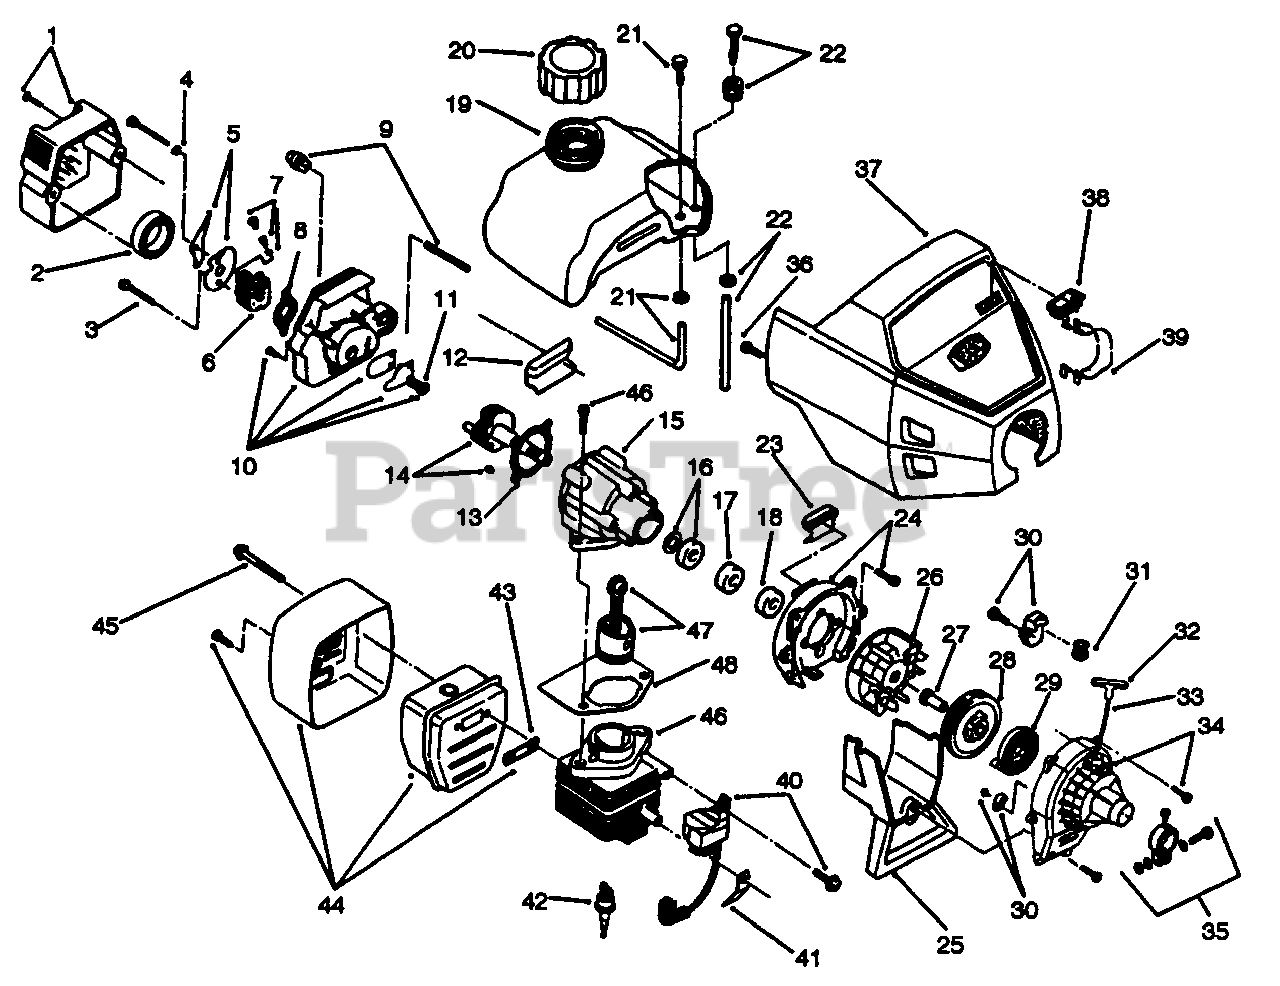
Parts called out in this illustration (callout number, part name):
1	Assy.-Carburetor/Air Clean (Inc. Ref. No.2)
2	Filter-Air Cleaner
3	Screw-Carburetor
4	Washer-Wave
5	Choke-Lever and Plate
6	Assembly-Carburetor
7	Throttle Adj.-Walbro
8	Gasket-Carb. (10 Pack)
9	Assy.-Primer and Hose
10	Assembly-Carb. Mount (Incl. Ref. No. 11 & 13)
11	Assembly-Reed
12	Pad-Mounting, Rear
13	Gasket (10 Pack)
14	Assembly-Power Shaft
15	Assy.-Crankcase (Incl. Ref. No.14-18)
16	Assembly-Inner Bearing
18	Assembly-Outer Bearing
19	Assemby-Fuel Tank (Incl. Ref. No.20-22)
20	Assembly-Fuel Cap
21	Assembly-Return Line
22	Assembly-Fuel Line
23	Pad-Mounting, Front
24	Assembly-Shroud
25	Shroud Extension & Stand
26	Assembly-Flywheel
27	Square Nut Drive
28	Assembly-Recoil Pulley
29	Spring-Recoil
30	Assembly-Pulley Retainer
31	Guide-Rope
32	Handle-Pull
34	Assembly-Starter Housing
35	Assembly-Upper Clamp
36	Screws-Engine Cover
37	Assembly-Engine Cover
39	Lead Wires
40	Assembly-Module
41	Tab-Ground
42	Spark Plug
43	Gasket-Exhaust (10 Pack)
44	Assembly-Muffler
45	Bolt-Muffler
46	Assembly-Cylinder (Incl. Ret. No. 48)
47	Assembly-Piston & Rod
48	Gasket-Cylinder (10 Pack)
